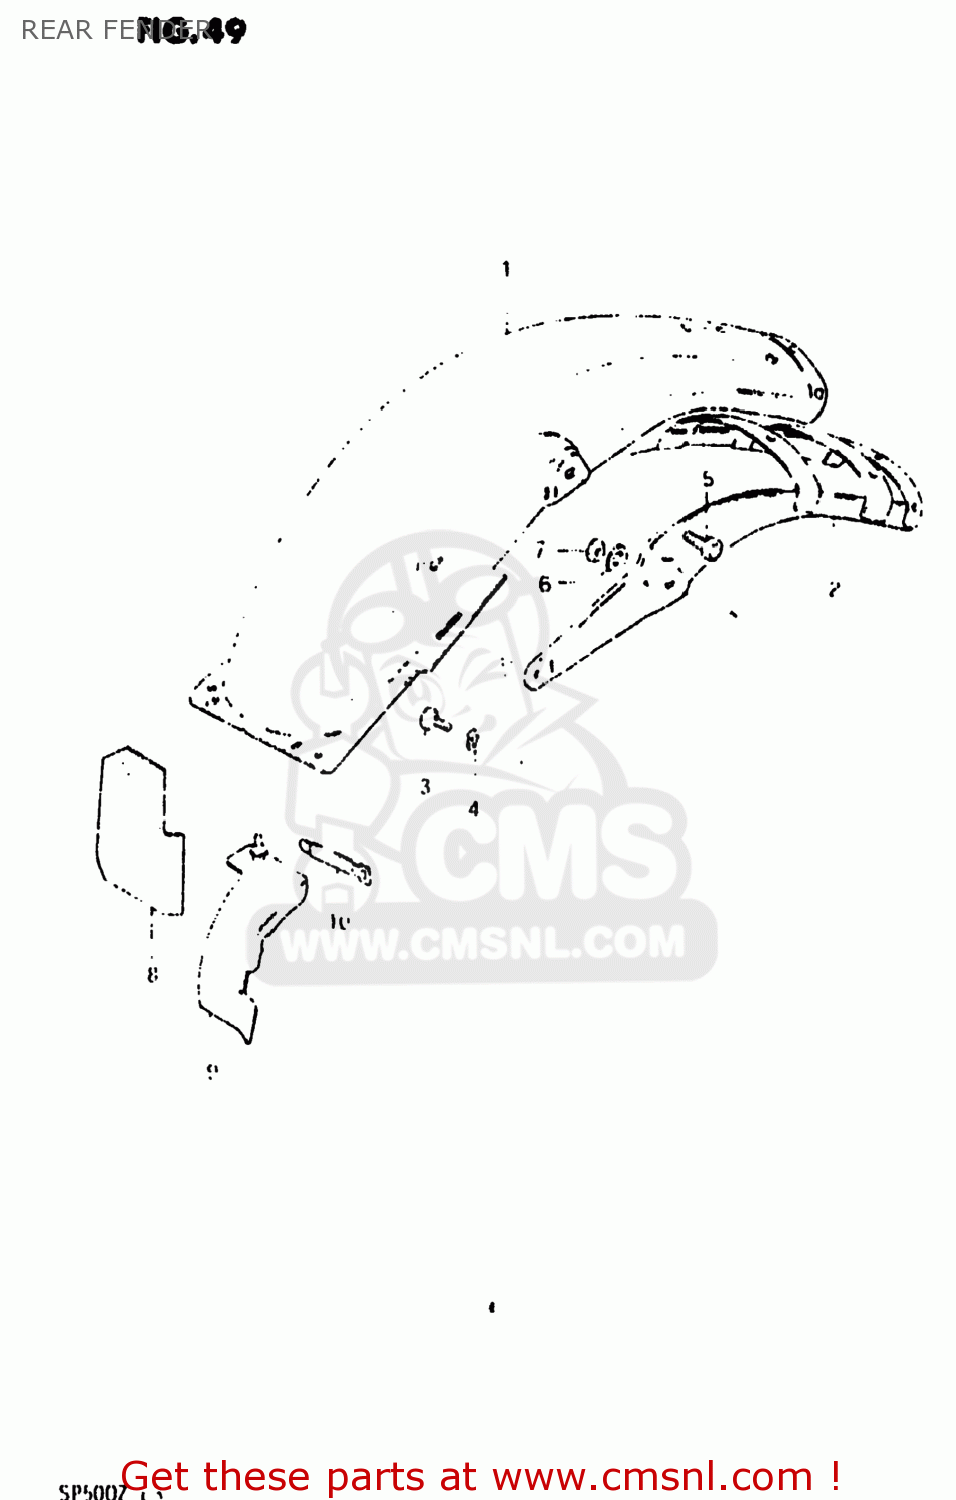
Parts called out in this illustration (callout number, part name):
1	FENDER,REAR
2	REINFORCEMENT,REAR FENDER
3	BOLT
4	LOCK WASHER
5	BOLT (8X30)
6	WASHER
7	NUT
8	MUD GUARD,REAR FENDER
9	MUD GUARD,REAR FENDER
10	CLAMP L:110
